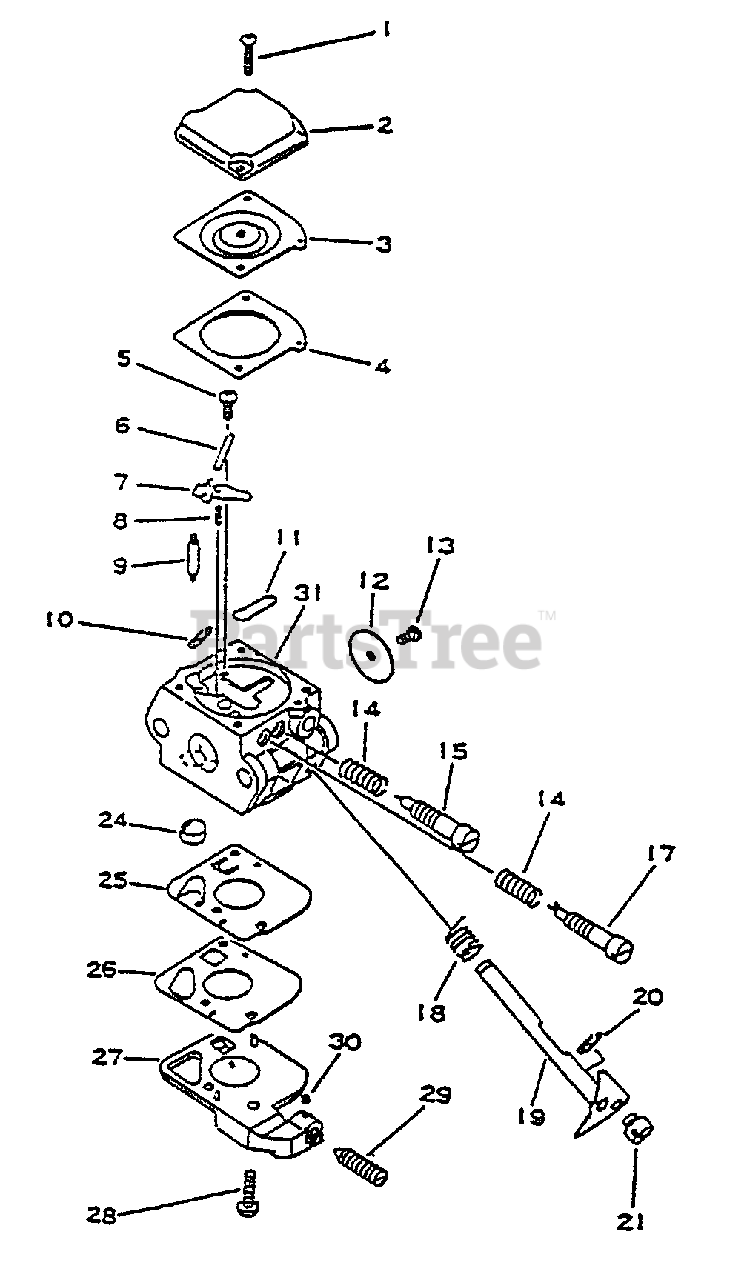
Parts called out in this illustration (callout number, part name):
2	COVER, DIAPHRAGM
3	DIAPHRAGM
4	GASKET, METERING
6	PIN, METERING LEVER
7	LEVER, METERING
8	SPRING
9	VALVE, NEEDLE
11	PLUG, WELCH
12	VALVE, THROTTLE
13	SCREW
14	SPRING, NEEDLE
15	NEEDLE, HIGH SPEED
17	NEEDLE, LOW SPEED
18	SPRING, THROTTLE RETURN
19	SHAFT, THROTTLE
24	STRAINER
27	COVER, PUMP
29	SCREW, IDLE ADJUST
30	PIECE, FRICTION
